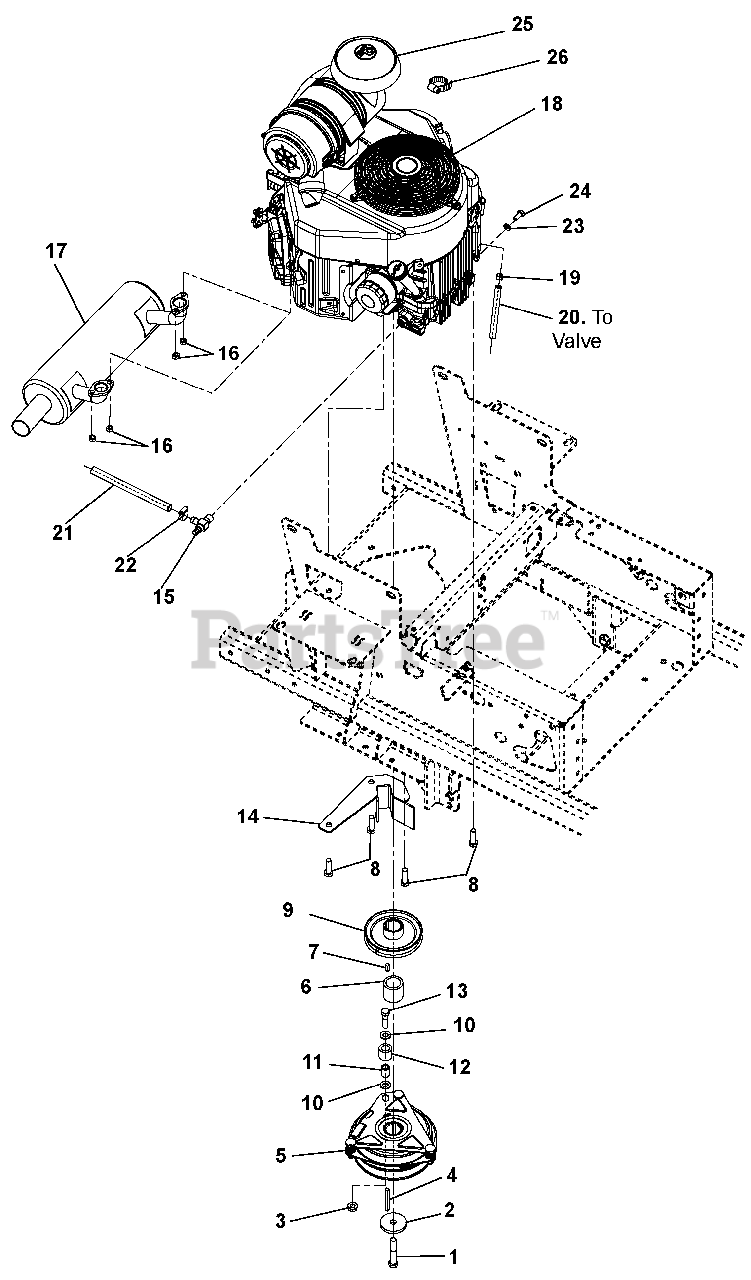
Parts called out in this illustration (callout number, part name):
1	Bolt, Hex .44-20 x 2.50
2	Washer, Flat-Steel .469 x 2.00 x .25
3	Nut, Locking-Top-Flange .38-16
4	Key .25 x .25 x 2.25
5	Clutch, Ogura GT2.5-FE02
6	Spacer, 1.125 x 1.50 x 1.40
7	Key, Square .25 x .625 x .25 SAE 8630 or SAE 1035
8	Bolt, Hex .38-16 x 1.25 FTH
9	Pulley, 4.50 OD x 1.127 Engine
10	Washer, Flat-Steel .406 x .812 x .065
11	Bushing, Sleeve .407 x .625 x .813 Steel
12	Bumper, Rubber .62 x 1.0 x .88 LG Engine
13	Bolt, Hex .38-16 x 1.50
14	100I Clutch Stop Weldment
15	Drain, .50 Oil
16	Nut, Locking-Top M8-1.25
17	Muffler, Kawasaki Fixed
18	Engine, Kawasaki FX691
19	Clamp, Fuel Line
20	Hose, .25 Low-PERM Bulk Gas
21	Tube, Oil Drain 8" Clear Vinyl
22	Clamp, .88 Diameter Hose
23	Washer, Locking .31 x .078 Regular
24	Bolt, Hex M8-1.25 x 20
25	Cap, Air Cleaner Rain
26	Clamp, Hose 2.75 Dia. Worm
